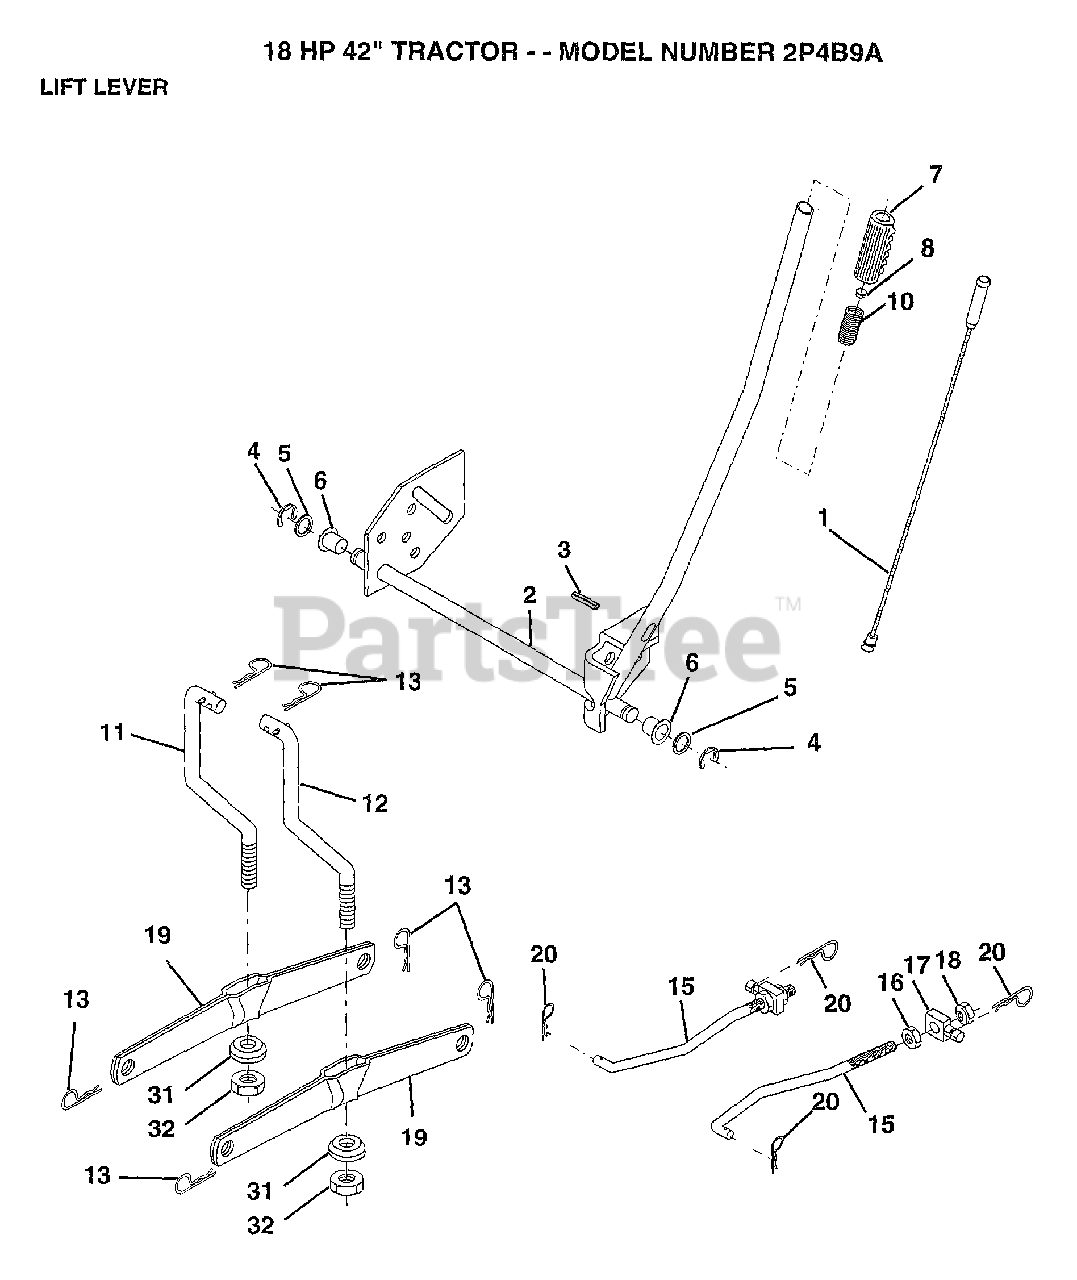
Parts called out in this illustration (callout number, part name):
1	WIRE ASM
3	PIN-GROOVE LT
5	WASHER
6	NYLON BEARING
7	GRIP
15	LINK.FRONT
16	NUT
17	TRUNION
18	NUT.LK.W/WSH.1/2.
19	ARM SUSP REAR
20	RETAINER.SPRING
31	BEARING PVT LH
32	NUT.LOCK.3/8-24
